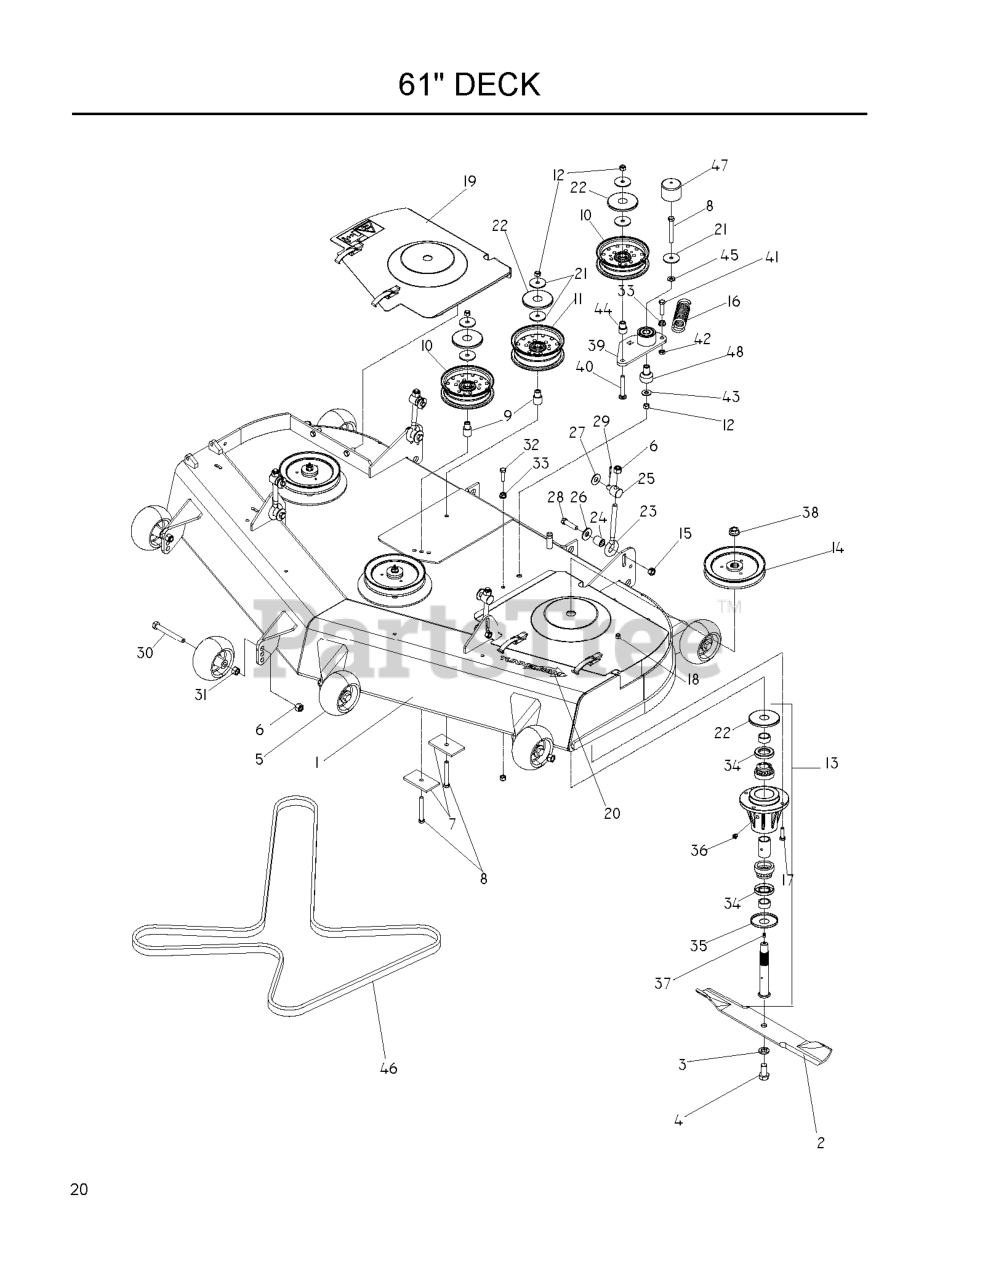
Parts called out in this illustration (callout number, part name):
1	DECK W/DECALS 61" HUS
2	BLADE OEM 21" (61" DECK)
3	LOCKWASHER 5/8
4	HCS 5/8F X 1 1/4
5	GAUGE WHEEL
6	NUT 1/2-13 HEX NYLOC ZD
7	SUPPORT PLATE
8	HCS 3/8C X 3
9	IDLER BUSHING
10	IDLER PULLEY
11	IDLER PULLEY (TALL)
12	NUT 3/8-16 NYLOC
13	HSG KIT 52/61 RIBBED
14	PULLEY, 61
15	NUT 7/16C CENTERLOCK
16	DECK SPRING
17	HCS 5/16C X 1 1/4
18	NUT 5/16 NYLOC
19	61 BELT SHIELD ASM - RH
19	61 BELT SHIELD ASM - LH
20	DECAL, TUNNEL RAM 8"
21	WASHER, 3/8 SPEC
22	TOP DUST CAP
26	SPRING WASHER - .50
27	WASHER 1/2 FLAT
28	HCS 7/16 - 14 X 1 3/4
29	PIN COTTER 1/8 X 1 ZD
30	HCS 1/2-13 X 4 GR 5 ZD
31	NUT HEX 1/2
32	HCS 3/8C X 1 1/4 GR5
33	NUT 3/8C WHIZ
34	SHAFT SEAL
35	BOTTOM DUST CAP
36	PLUG-VENTED
38	NUT FLANGE 3/4-16
39	ARM-IDLER W/BRG
40	RHSNB 3/8-16 X 2.75
41	HCS 3/8-16 X 1-1/2
42	NUT 3/8-16 HEX JAM
43	WASHER 3/8 FLAT
44	BUSHING, IDLER
45	WASHER 3/8 SAE FLAT
46	DECK BELT 61
47	CAP, VINYL
48	PIVOT, BEARING
